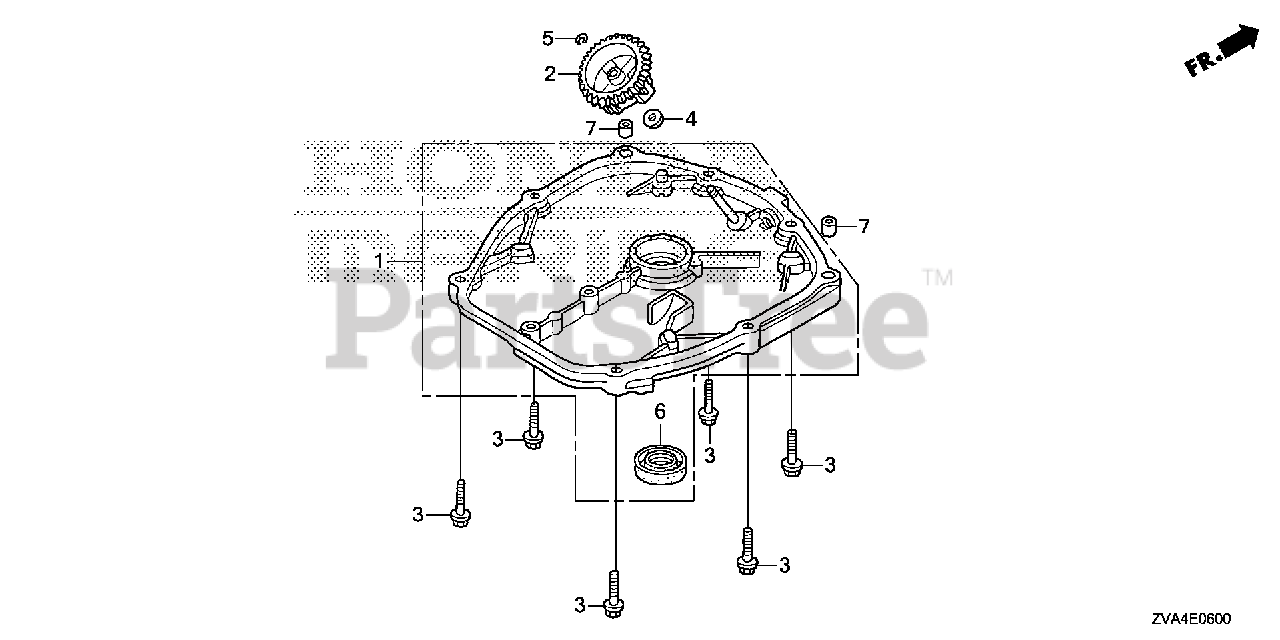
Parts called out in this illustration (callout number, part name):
1	COVER COMP
1	COVER, CRANKCASE SIDE
2	HOLDER, GOVERNOR WEIGHT
2	HOLDER, GOV WEIGHT
3	BOLT, FLANGE (5X23) (CT200)
4	WASHER (4.2X13)
5	CLIP, GOVERNOR HOLDER
5	CLIP, GOV HOLDER
6	OIL SEAL (17X27X5) (KOYO)
7	PIN A, DOWEL (6X10)
